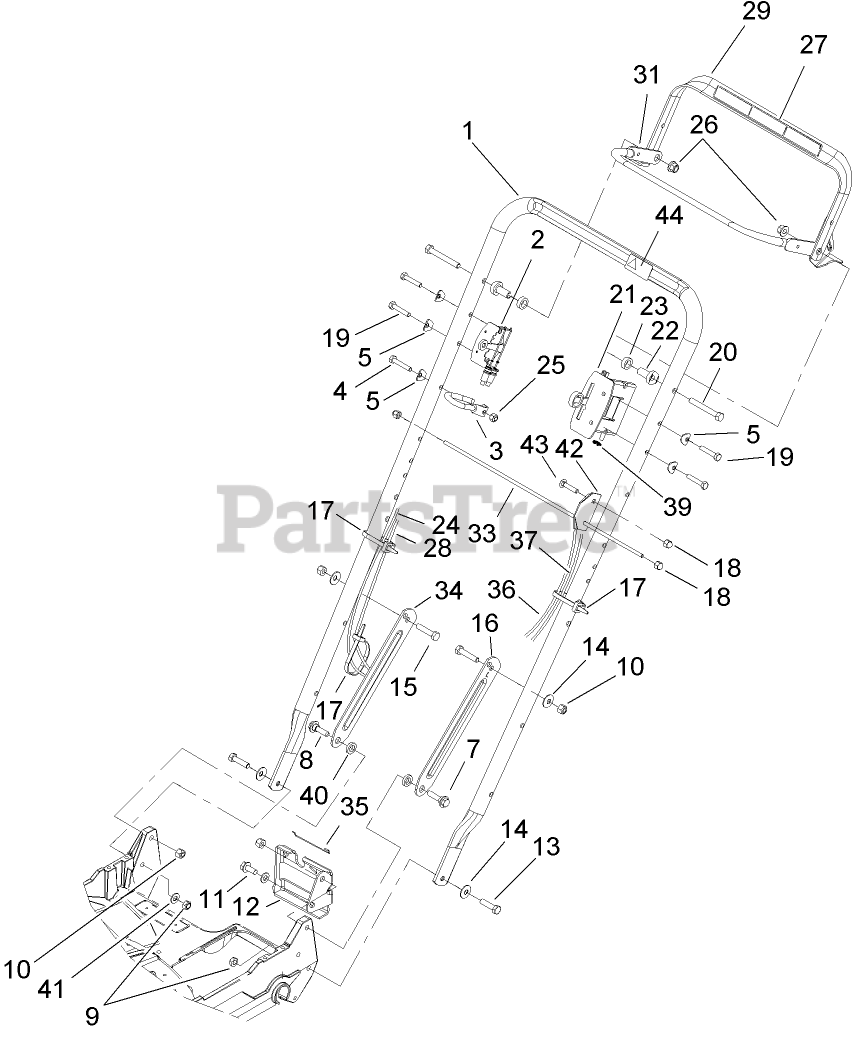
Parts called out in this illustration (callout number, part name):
1	HANDLE-PROLINE
3	GUIDE-ROPE
4	SCREW-HH
5	WASHER
7	SCREW-SHOULDER
8	SPACER
9	NUT-LOCK, NI
10	NUT-LOCK, NI
11	SCREW-HWHTF
12	BRACKET-ADJUSTMENT, TRACTION
13	SCREW-HH
14	WASHER-BELLEVILLE
15	SCREW-HH
16	LATCH-HANDLE, LH
17	TIE-CABLE
18	NUT-CAP
19	SCREW-HH
20	SCREW-HH
22	SPACER-SUPPORT
23	SPACER-NYLON
24	CABLE-BRAKE
25	NUT-LOCK, NI
26	NUT-LOCK, NI
27	DECAL-OPERATION
28	CABLE-SHIFT
29	TRACTION BAIL ASM
31	BRAKE BAIL ASM
33	ROD-SUPPORT, BAG
34	LATCH-HANDLE, RH
35	RETAINER-CABLE
36	CABLE-TRACTION
37	THROTTLE CABLE ASM
39	E-RING
40	SCREW-SHOULDER
41	WASHER-PLAIN
42	PLATE-ALIGNING, BAG
43	SCREW-CARR
44	DECAL-PROTECTION, EAR
